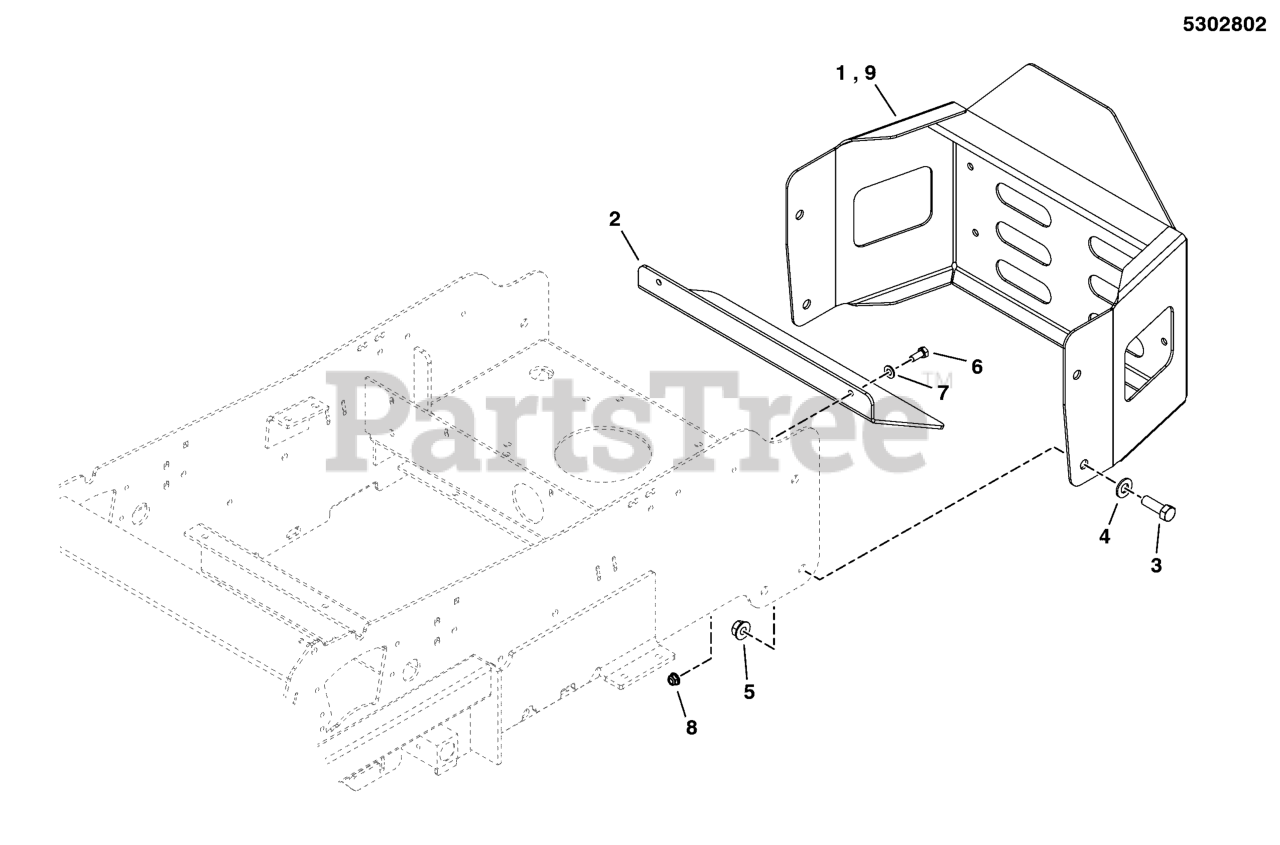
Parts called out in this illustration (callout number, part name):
1	WELD, PLATE, BUMPER - RED
2	SHIELD, MUFFLER - BLK
3	BOLT, 1/2-13 X 1-1/2 GD5 CZ
4	WASHER, 1/2 SAE
5	NUT, Hex Flange, Nylock, 1/2-13
6	BOLT, 5/16-18 X 3/4 GD5
7	WASHER, 5/16" SAE
8	NUT, 5/16-18 HEX NYLOCK FLANGE
9	WELD, PLATE, BUMPER - RED
